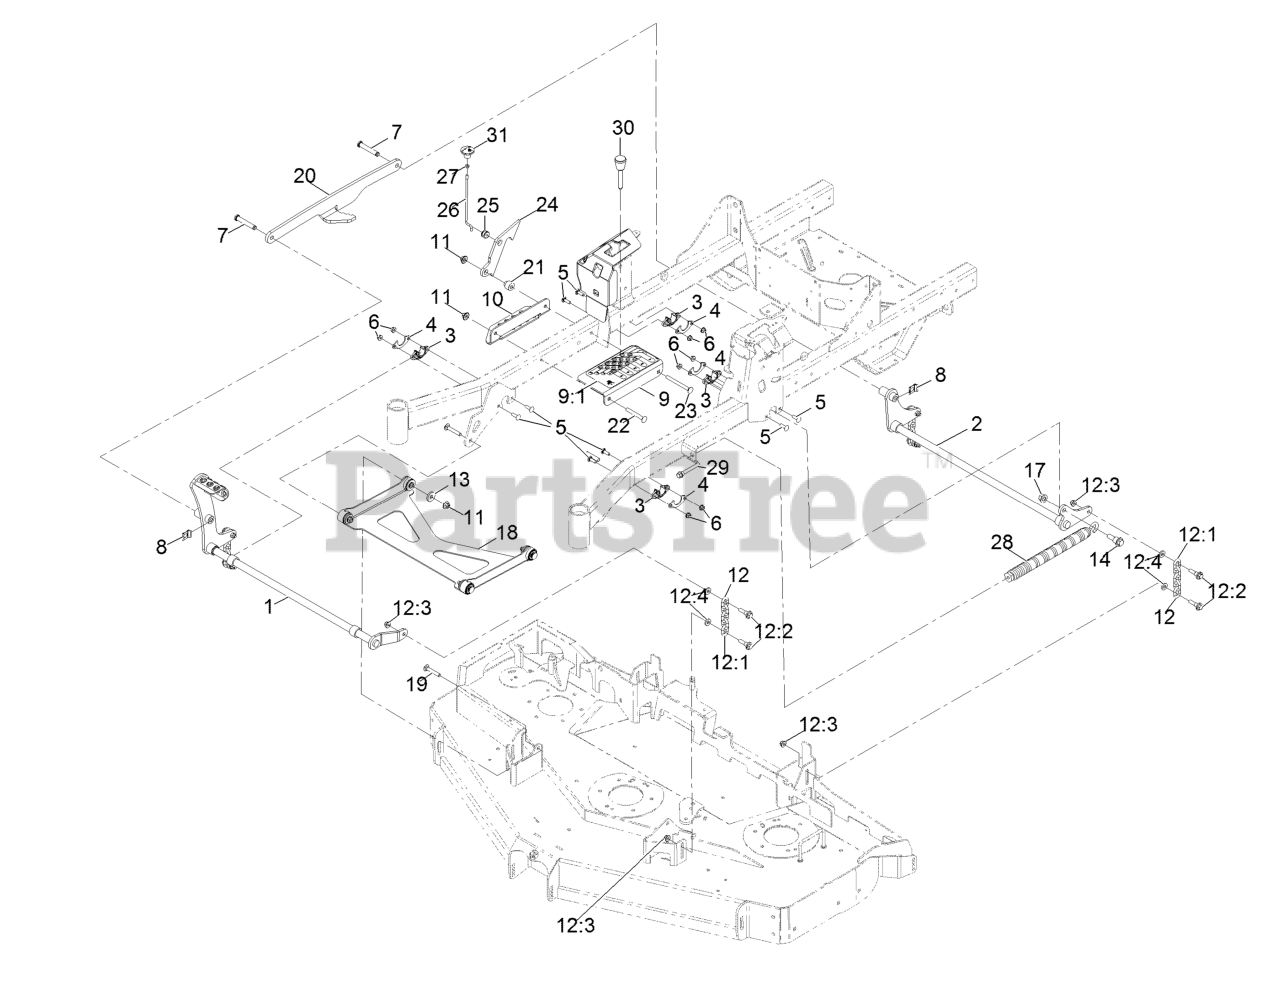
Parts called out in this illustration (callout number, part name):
1	Shaft-Lift, Deck
2	Shaft-Lift, Deck (Rear)
3	Bushing-Flange
4	Gusset-Lift, Deck
5	Bolt-Carriage 5/16-18 X 1 Sp
6	Nut-Nyloc 5/16-18 Flg
7	Pin-Clevis
8	Clip-Pin
9	Bracket ASM
9:1	Decal-HOC
10	Angle-HOC, Lower
11	Nut-Nyloc 3/8-16 Flg
12	Deck Chain ASM
12:1	Chain-Lift, Deck
12:2	Bolt-Shoulder
12:3	Nut-Nyloc 3/8-16 Flg
14	Screw-Shoulder HHF 1/2-13 X 1.12
17	Nut-Lock 1/2-13
18	Deck Strut ASM
19	Bolt-Carriage 3/8-16 X 2 1/4
20	Link-Lift
21	Spacer-Stepped
22	Bolt-Carriage 3/8-16 X 3
23	Screw-CARR
24	Plate-Lock, Transport
25	Grommet
26	Rod-Lock, Transport
27	Nut-Jam 1/4-20
28	Spring-Extension
29	Screw-Shcs 3/8-16 X 2.212
30	Pin-HOC
